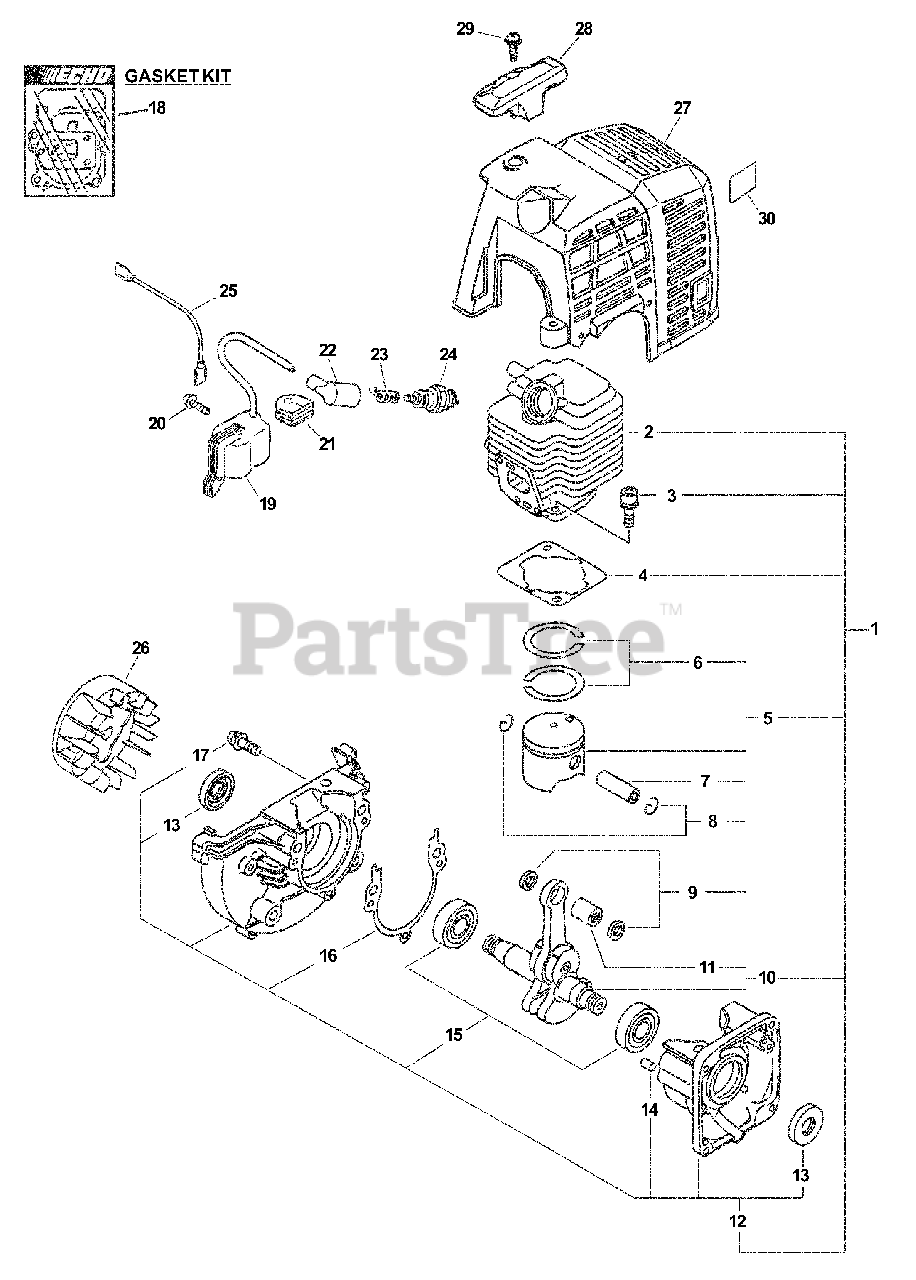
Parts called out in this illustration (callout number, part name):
1	SHORT BLOCK ES-2100;PB-2100
2	CYLINDER
3	BOLT 5×22
4	GASKET, CYLINDER
5	PISTON KIT
6	RING, PISTON
7	PIN, PISTON 8
8	RING, SNAP
9	WASHER, THRUST
10	CRANKSHAFT ASSY
11	BEARING, NEEDLE
12	CRANKCASE KIT
13	SEAL, OIL 12
14	PIN, LOCATING 4
15	BEARING, BALL - 6201 C3
16	GASKET, CRANKCASE
17	BOLT 5×28
18	GASKET KIT
19	COIL, IGNITION
20	SCREW 4×22
22	CAP, SPARK PLUG
23	TERMINAL, SPARK PLUG
24	SPARK PLUG - BPM7A
24	SPARK PLUG - RCJ7Y
25	LEAD
27	COVER, ENGINE
28	GUARD, TOP
29	SCREW 5×16
30	LABEL, CAUTION - HOT
